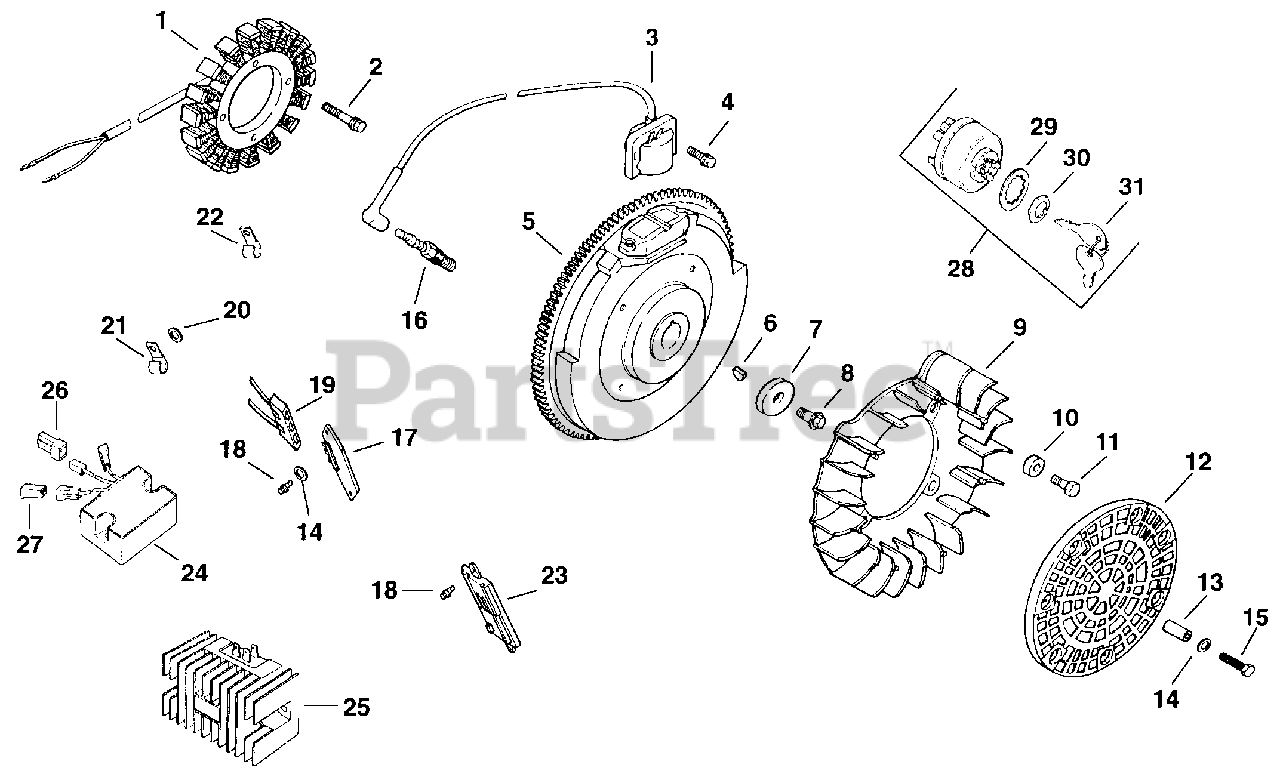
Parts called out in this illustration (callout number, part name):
1	KIT - USE 54 755 09
2	SCREW - USE M-548025
4	Screw, hex. flange M5x0.8x20
6	KEY, 3/16" X 5/8"
7	WASHER, FLAT 13/32"
8	SCREW, FLG M10X1.5X45 - (#25086361S)
9	FAN (KM)-USE 24 157 15-S
10	BOLT - USE 25 086 47
11	SCREW - USE M-639016
12	KIT - USE 54 755 15
13	SPACER - DISCONTINUED
14	WASHER, FLAT 3/16"
15	Screw, hex. cap M6x0.7x25
16	PLUG, SPARK (STD)
18	SCREW, PHL HD #11-16X7/8"
19	CONNECTOR, BODY (KM)-USE 25 155 41-S
20	WASHER, FLAT 1/4" (O.D. 1/2")
28	SWITCH ASSY, KEY (KM)-USE 25 099 32-S
29	WASHER, INTERNAL TOOTH
30	NUT, KEY SWITCH
31	Key (Set of 2)
2417630	KIT - USE 54 755 02
2451804	LEAD - USE 25 518 34
2451806-S	LEAD - DISCONTINUED
